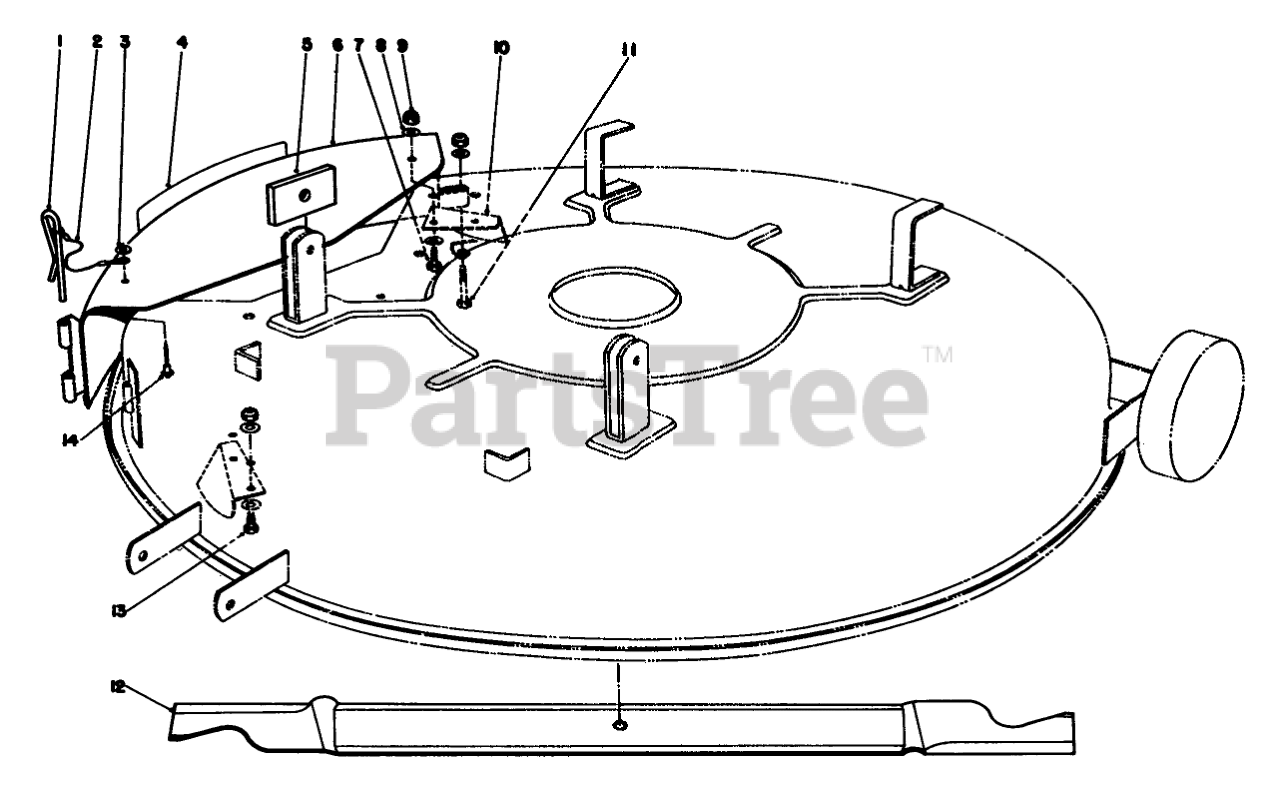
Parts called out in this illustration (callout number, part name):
1	PIN-LOCKING, CHUTE
2	LANYARD
3	WASHER-PLAIN
4	COVER DECAL
5	SPACER
6	Cover-Mulcher Assembly (Incl. Ref. #1-4 & 14)
7	SCREW-HH
8	WASHER-PLAIN
9	NUT-LOCK, NI
10	KICKER B
11	SCREW-HH
12	Blade
13	SCREW-HH
14	RIVET-BLIND
